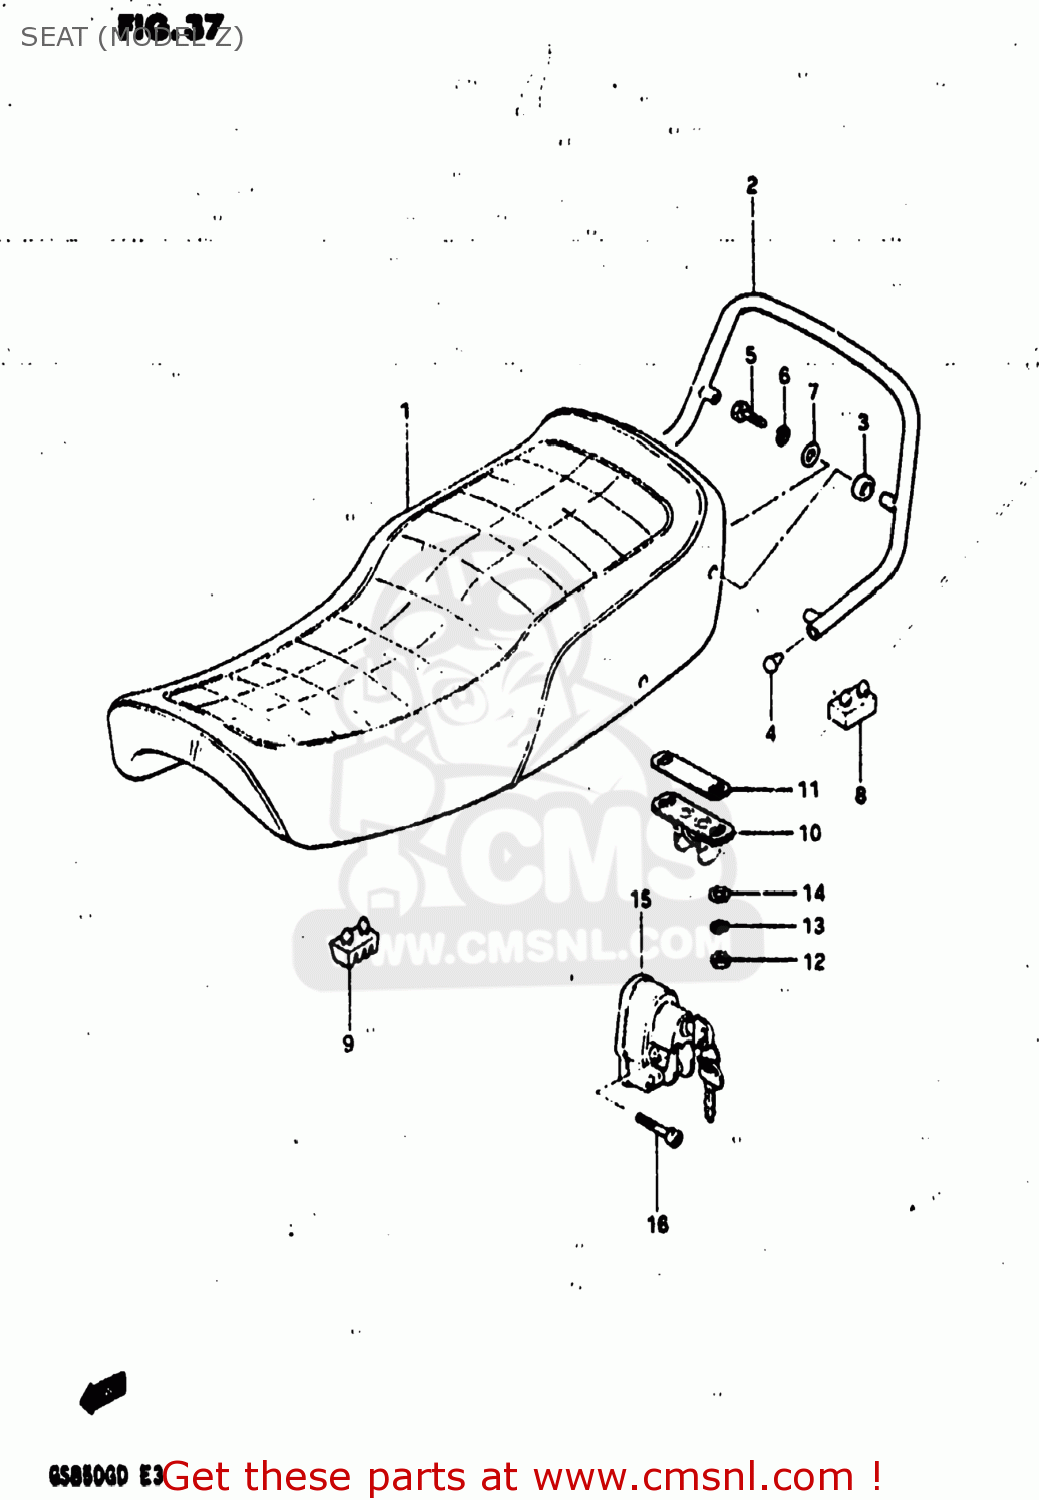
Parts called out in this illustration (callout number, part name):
1	SEAT ASSEMBLY
2	HANDLE,PILLION RIDER
3	CUSHION
4	END,SHEET HANDLE
5	BOLT
6	LOCK WASHER
7	WASHER
8	CUSHION(40X23X12.7)
9	CUSHION,SUPPORT(50X25X32)
10	STRIKER,SEAT LOCK
11	SHIM,SEAT LOCK STRIKER
12	NUT 6MM
13	LOCK WASHER
14	WASHER
15	LOCK ASSY,HELMET
16	BOLT 5X25
